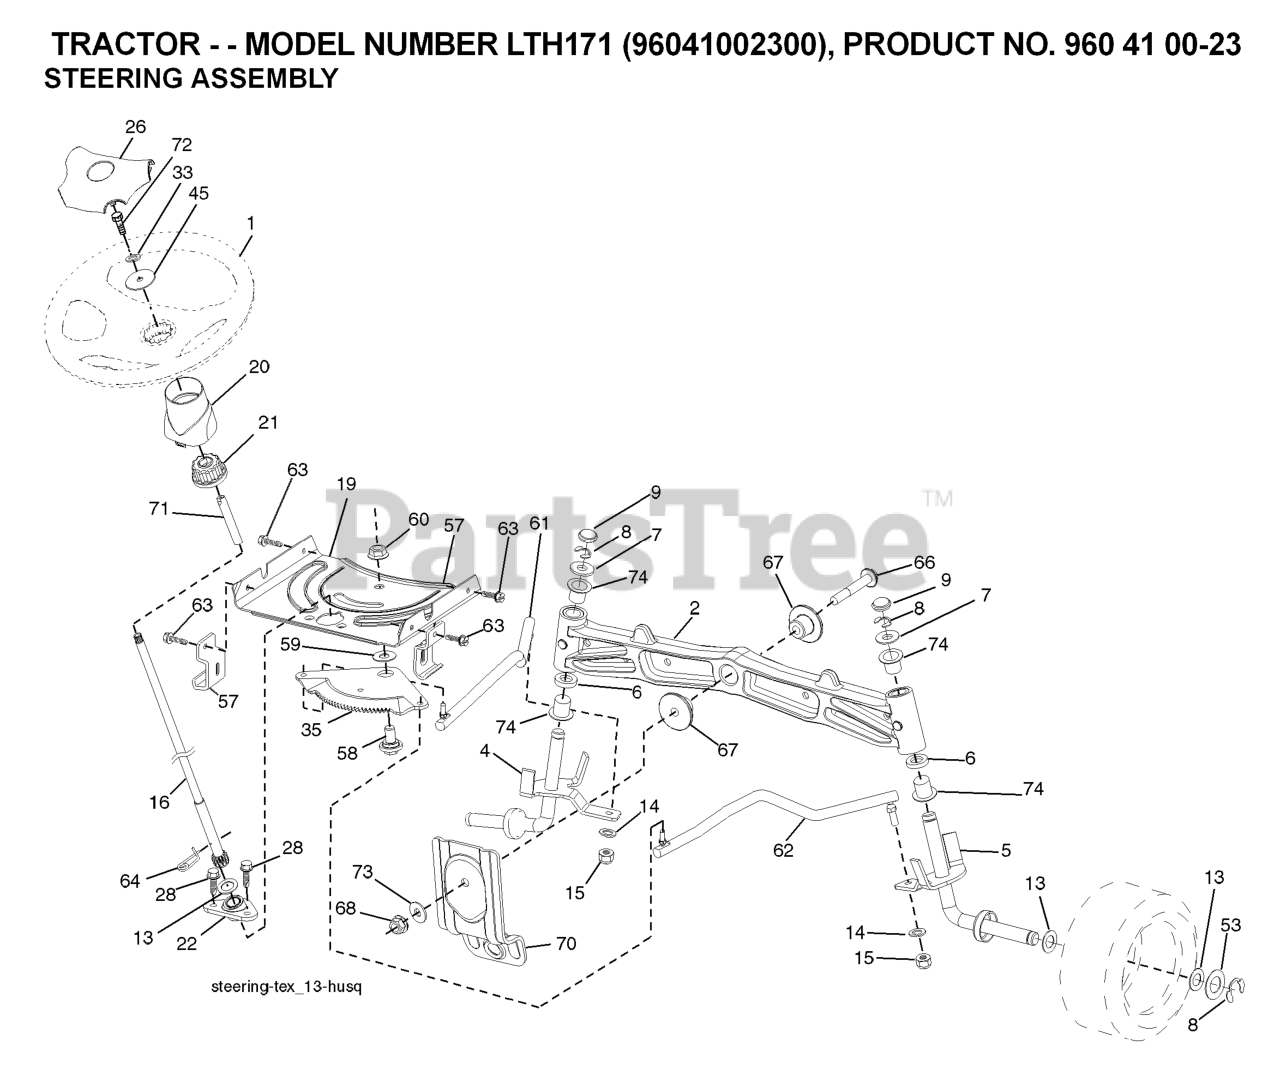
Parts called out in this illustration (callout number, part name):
1	STEERING WHEEL
2	AXLE.HALF.ASM.WELDED
4	SPINDLE.WELDED.LH.15"TEX
5	SPINDLE.WELDED.RH.15"T
6	THRUST WASHER
9	CAP.SPINDLE.BLACK
14	WASHER, LOCK 3/8
15	NUT CROWNLOCK 3/8-24
16	SHAFT STEERING
19	PLATE.STEER.DDL.NLT/NG
20	BOOT, STEERING
21	ADAPTER, WHEEL STNG..
22	BUSHING.ASM.STEERING.A
26	INSERT.CAP.STRG.WH.GRAY
28	SCREW, 3/8-16X3/4
33	WASHER.LOCK.HVY.HLCL.SPR.5/16
35	GEAR.SECTOR.PLATE.DDL.
45	WASHER.11/32
53	WASHER.HARDENED
57	BRACKET.UPSTOP.TEX
58	BOLT.SHOULDER.SECTOR.P
59	WASHER.THURST.SECTOR.S
60	NUT FLANGE LOCK 5/8-11
61	DRAGLINK.LH.BALLSTUD.D
62	DRAGLINK.RH.BALLSTUD.D
63	SCREW
64	RETAINER.CLIP.SPRING.S
66	BOLT HEX FGHD 7/16-14 X 3 SERR
67	BUSHING.PM.FRONT AXLE
68	NUT.LOCK.FLANGE.7/16
70	BRKT.DECK.SUSPENSION.F
71	SHAFT EXTENSION STEERING
72	BOLT YT
73	WASHER.1.5X.505X.118
74	BRNG T
